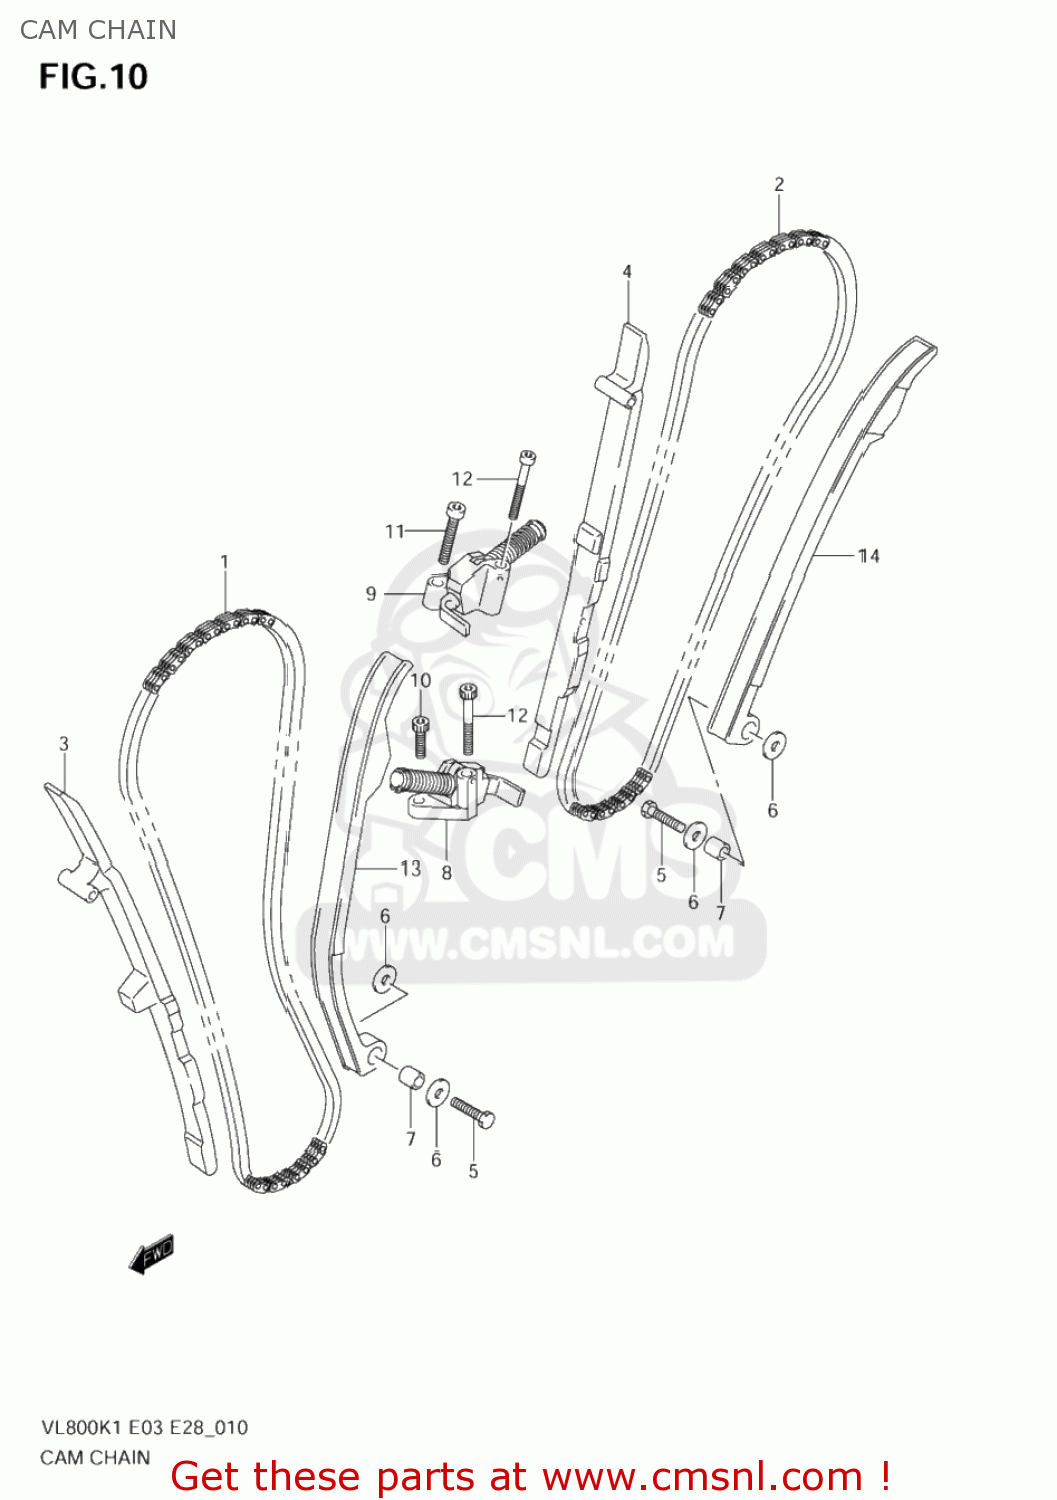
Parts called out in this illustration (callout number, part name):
1	CHAIN CAMSHAFT
2	CHAIN COMP,CAMSHAFT DRIVE
3	GUIDE,CAM CHAIN
4	GUIDE,CAM CHAIN RR
5	BOLT(6X26)
6	WASHER
7	SPACER(6X11X11)
8	ADJUSTER ASSEMBLY,FRONT TENSIONER
9	ADJUSTER ASSY,
10	BOLT,CRKCASE,R
11	BOLT
12	BOLT
13	TENSIONER,CAM CHAIN
14	TENSIONER,RR CAM CHAIN
